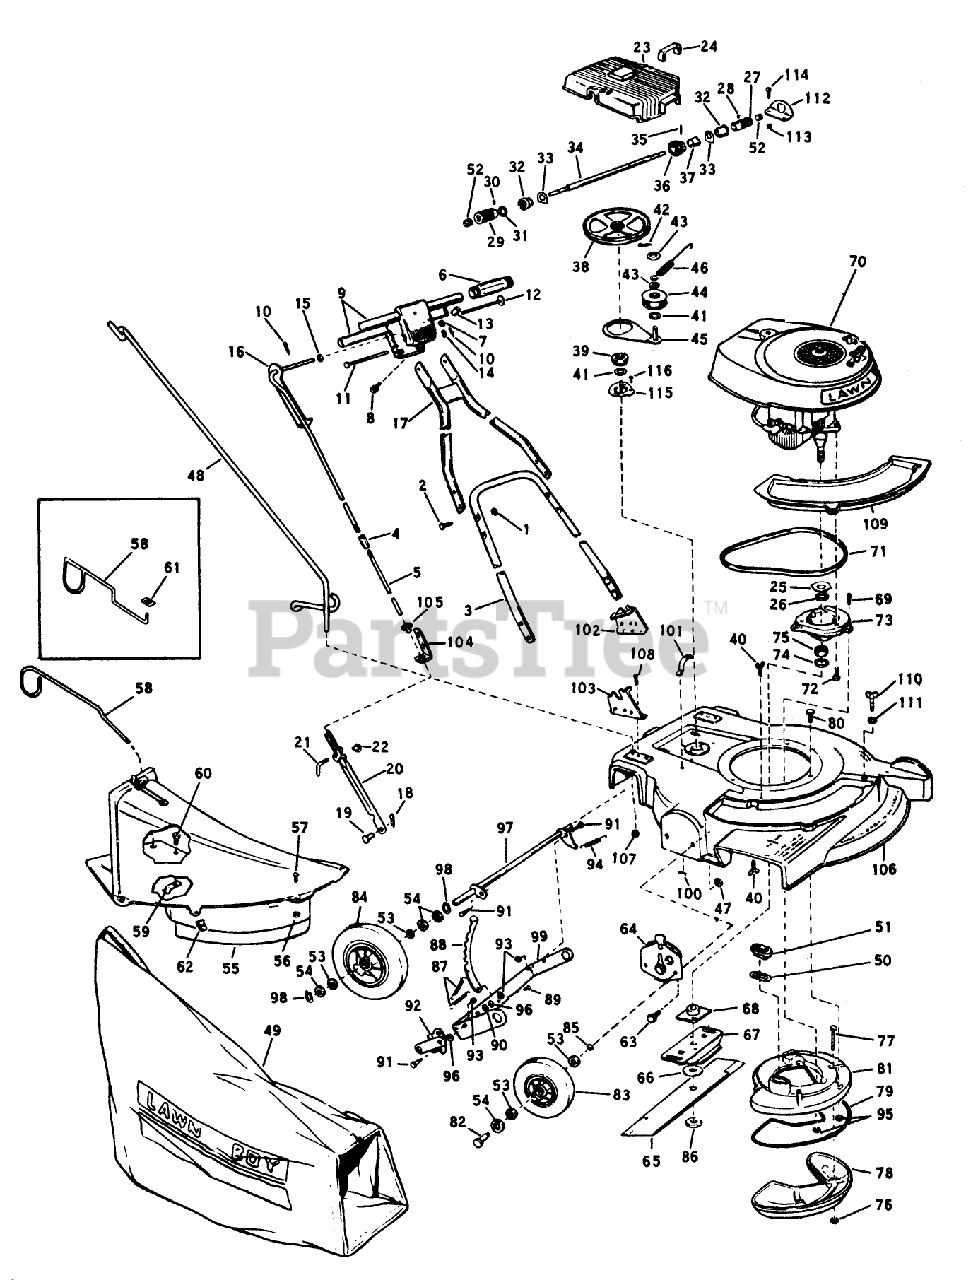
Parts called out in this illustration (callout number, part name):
10	Pin-Cotter
38	PULLEY&OILER FELT (13)
49	89802 LB WHOLE GOODS
50	GASKET S
52	GREASE PLUG
55	Chute Skirt Assembly (Includes Hardware)
62	SPEED NUT ARDEN
68	PLATE AND COLLAR ASM
76	LOCKNUT E
82	BOLT WHEEL
85	WASHER WROUGHT
86	NUT-BLADE
91	BOLT RB&W
93	STOP NUT
96	WASHER S
98	RETAINING RING
107	Nut--Nylok
108	SCREW S
